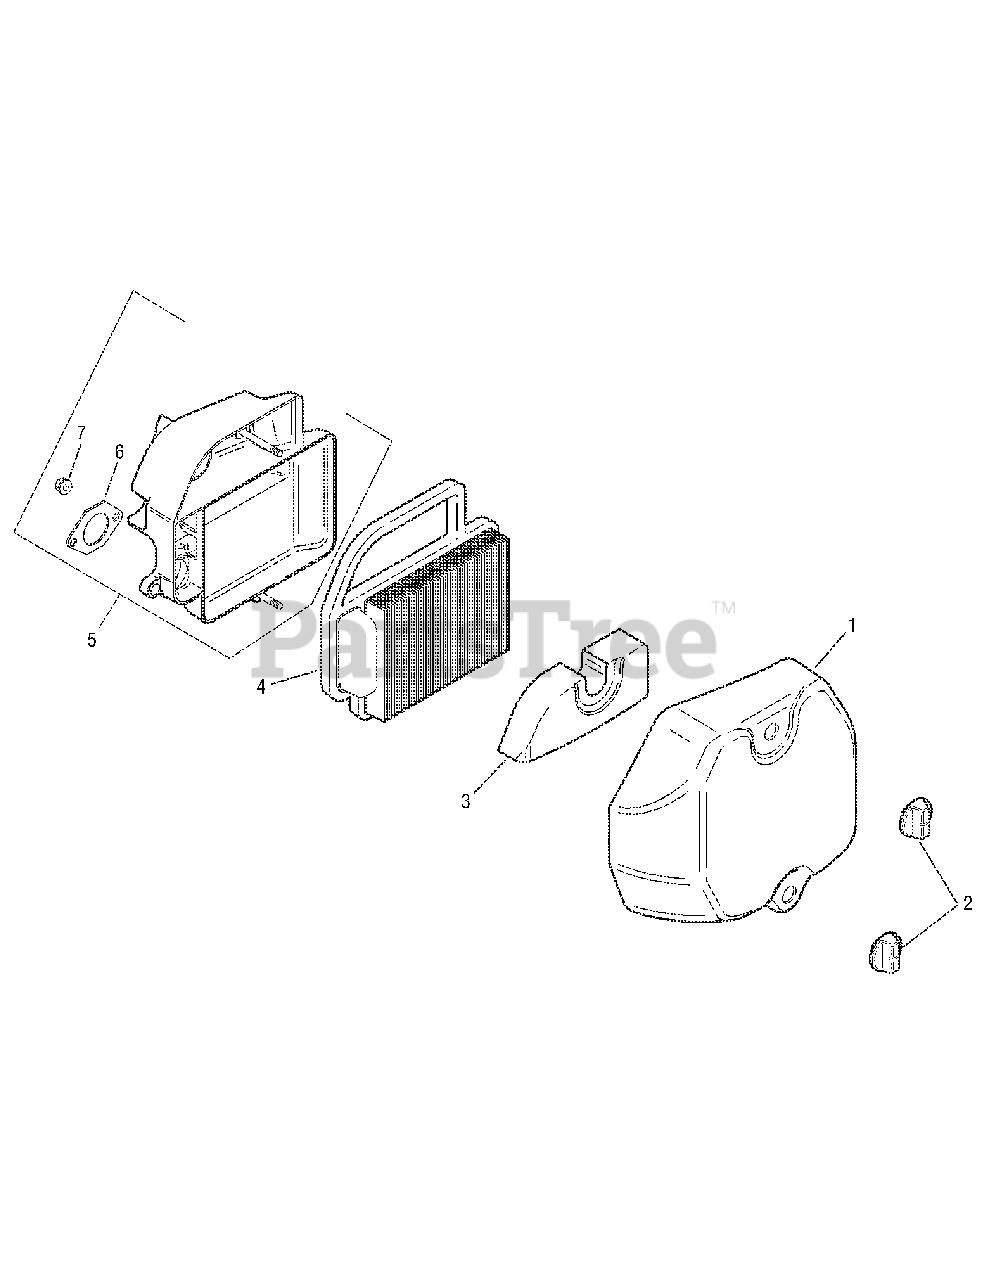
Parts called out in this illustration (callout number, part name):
1	Cover, air cleaner
3	Element, precleaner
4	Element, air cleaner
5	Kit, air cleaner base (Includes 6)
6	Gasket, air cleaner base
